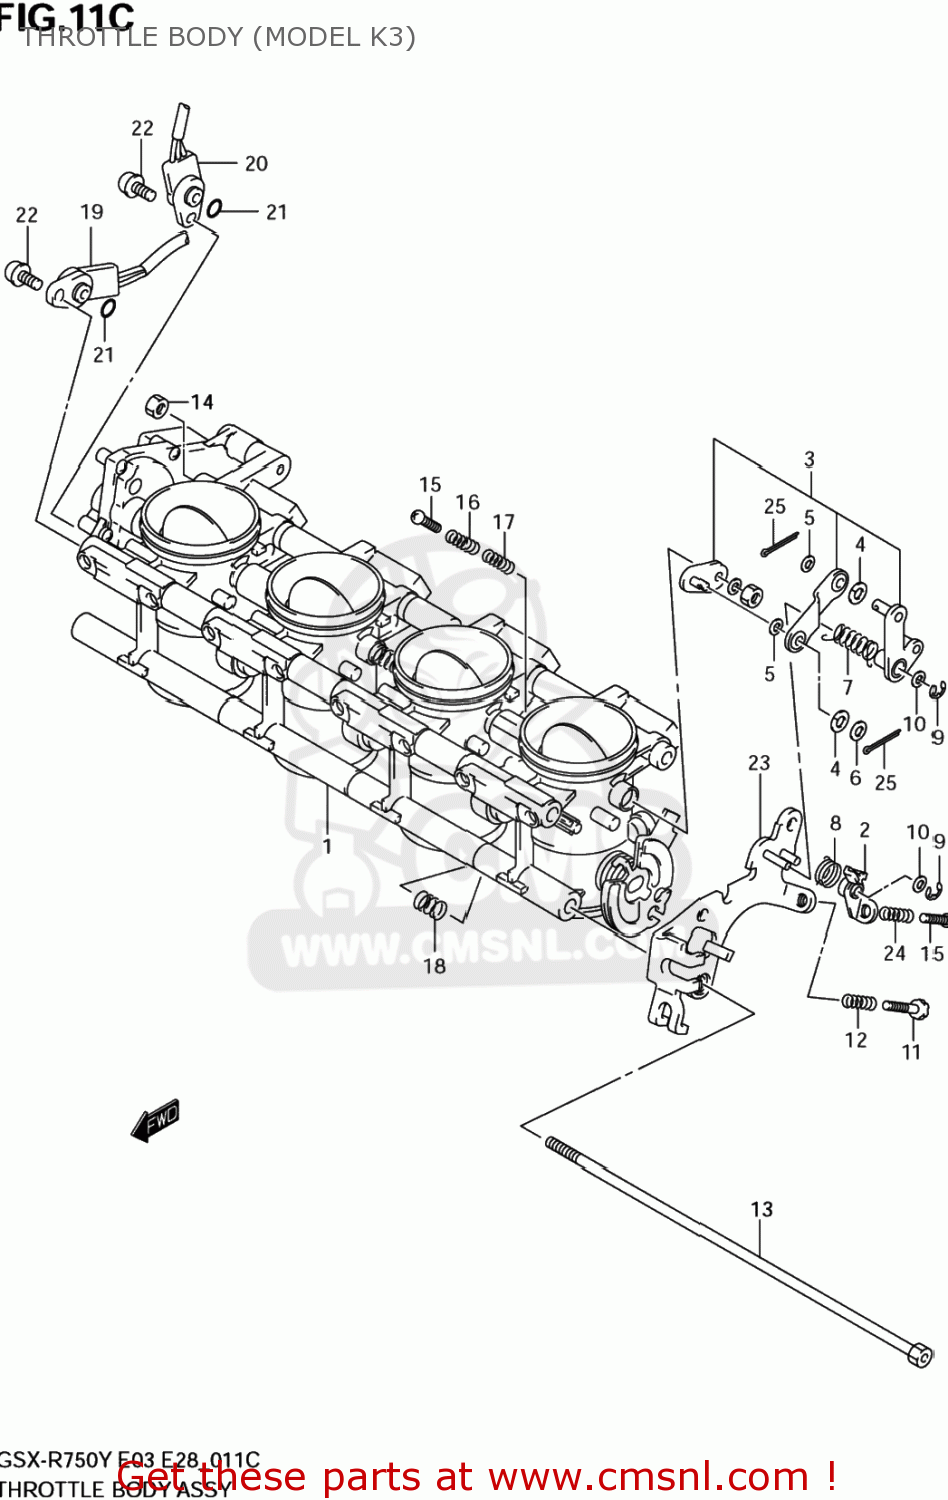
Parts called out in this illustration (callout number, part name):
1	BODY SET,THROTT
2	LEVER,LINK
3	LINK LEVER SET
4	WASHER
5	WASHER
6	WASHER
7	SPRING
8	SPRING
9	E CLIP
10	WASHER
11	SCREW,STOP
12	SPRING
13	BOLT
14	NUT
15	SCREW,STOP
16	SPRING
17	SPRING
18	SPRING
19	SENSOR ASSY,TH
20	SENSOR ASSY,TH
21	O RING
22	SCREW
23	PLATE,STAY
24	SPRING
25	PIN
